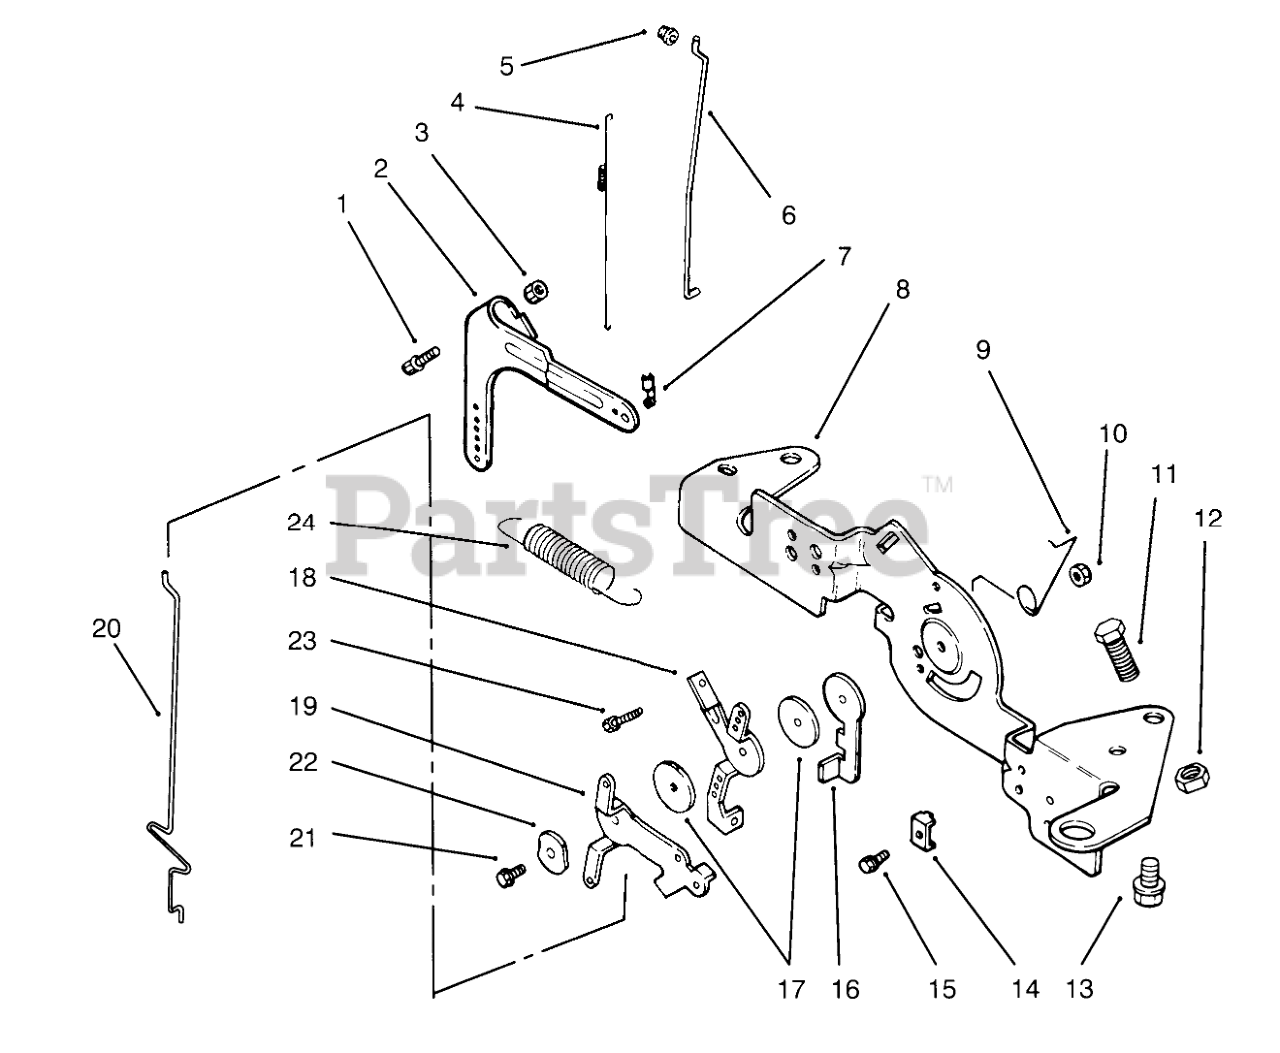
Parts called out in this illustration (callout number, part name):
1	Screw
2	Lever-Governor
4	Spring-Linkage
5	Bushing-Linkage
6	Linkage-Throttle
7	Bushing-Linkage
8	Bracket-Control
9	Spring-Choke Return
10	Nut
11	Screw
12	Nut
13	Screw
14	Clamp
15	Screw
16	Lever-Actuator, Throttle
17	Washer
18	Lever-Throttle Control
19	Lever-Choke
20	Linkage-Choke
22	Washer-Wave
24	Spring-Governor
